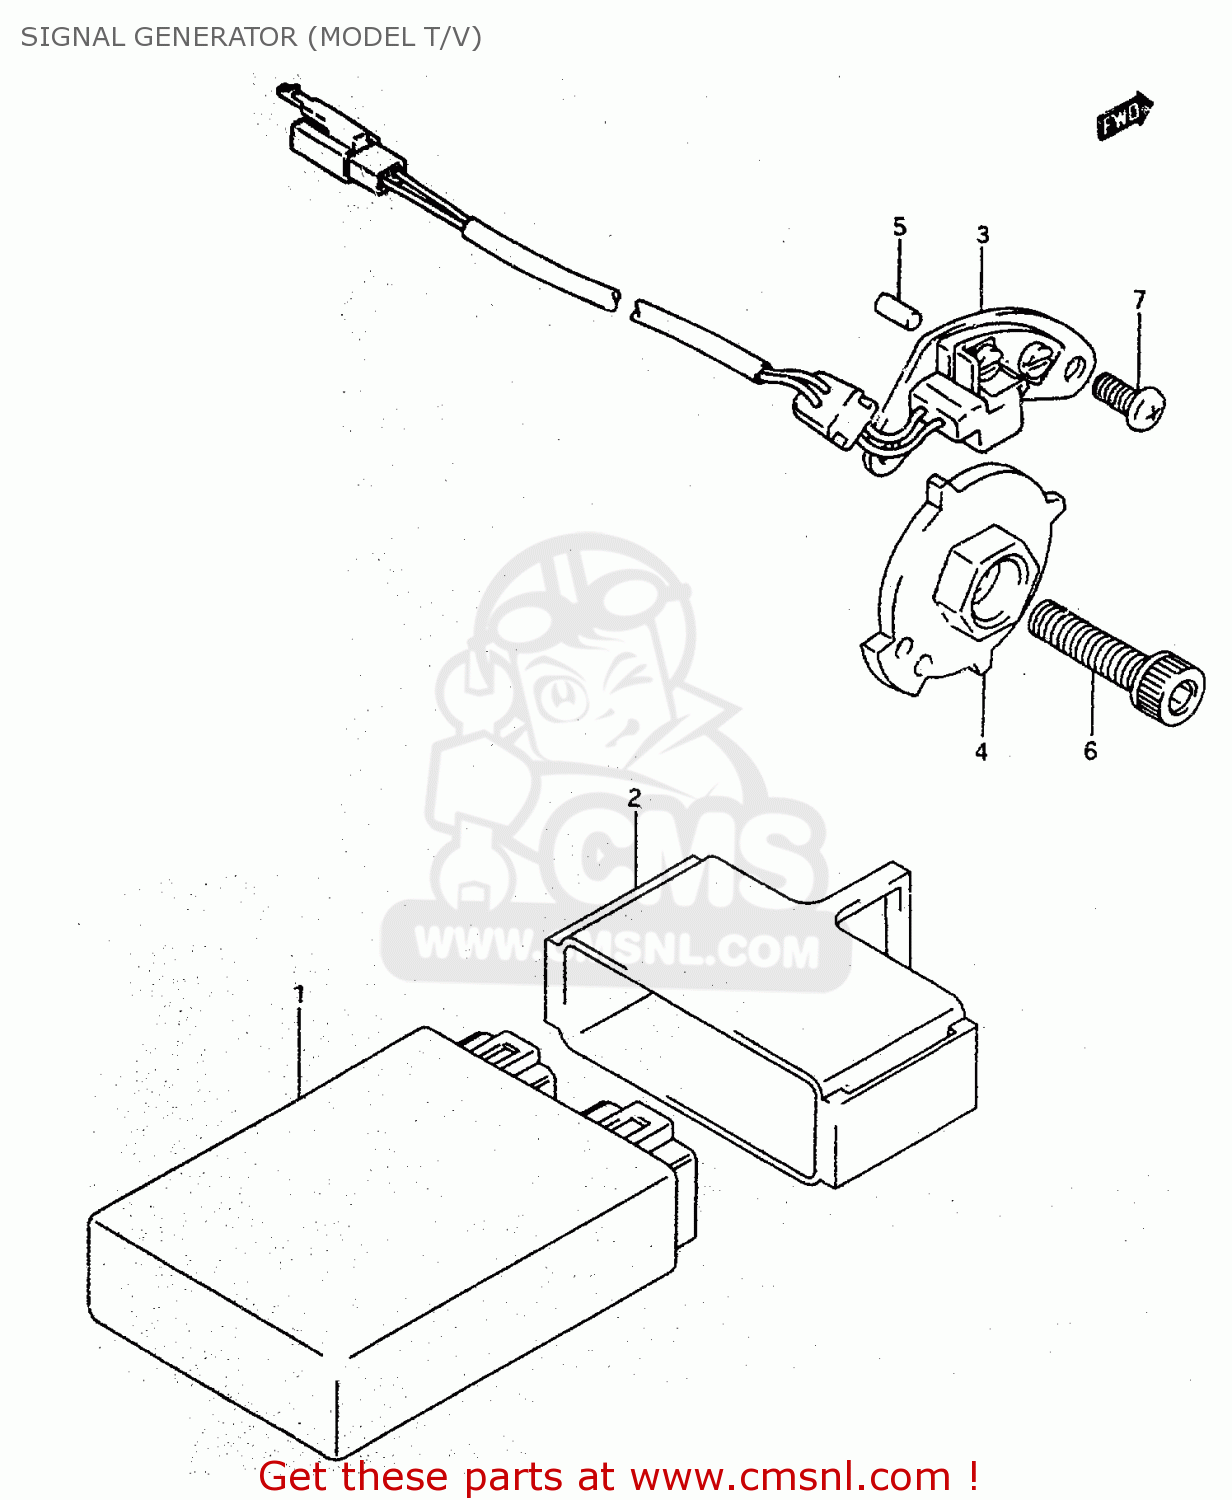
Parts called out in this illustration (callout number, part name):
1	IGNITER
2	CUSHION,IGNITOR
3	STARTER,SIGNAL GENERATOR
4	ROTOR,SIGNAL GENERATOR
5	PIN
6	BOLT
7	SCREW
